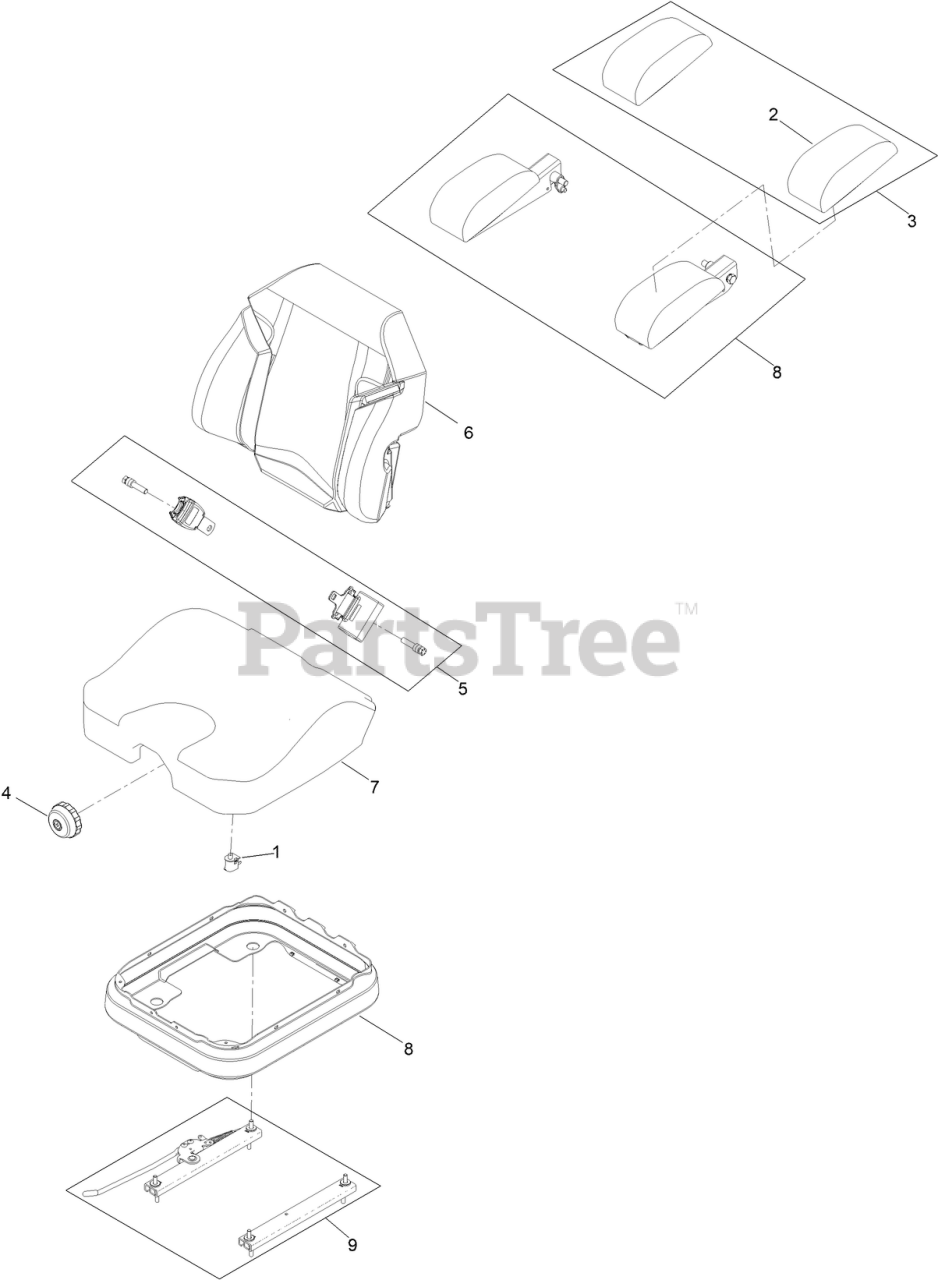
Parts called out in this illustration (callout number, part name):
1	SWITCH-BAIL
2	KIT-ARM REST PADS
3	KIT-ARM REST SET
4	KNOB-ADJUSTER
5	KIT-SEAT BELT
6	COVER-BACK
7	COVER-BOTTOM, SEAT
8	COVER-SUSPENSION BELLOWS
9	SET-SEAT TRACK
